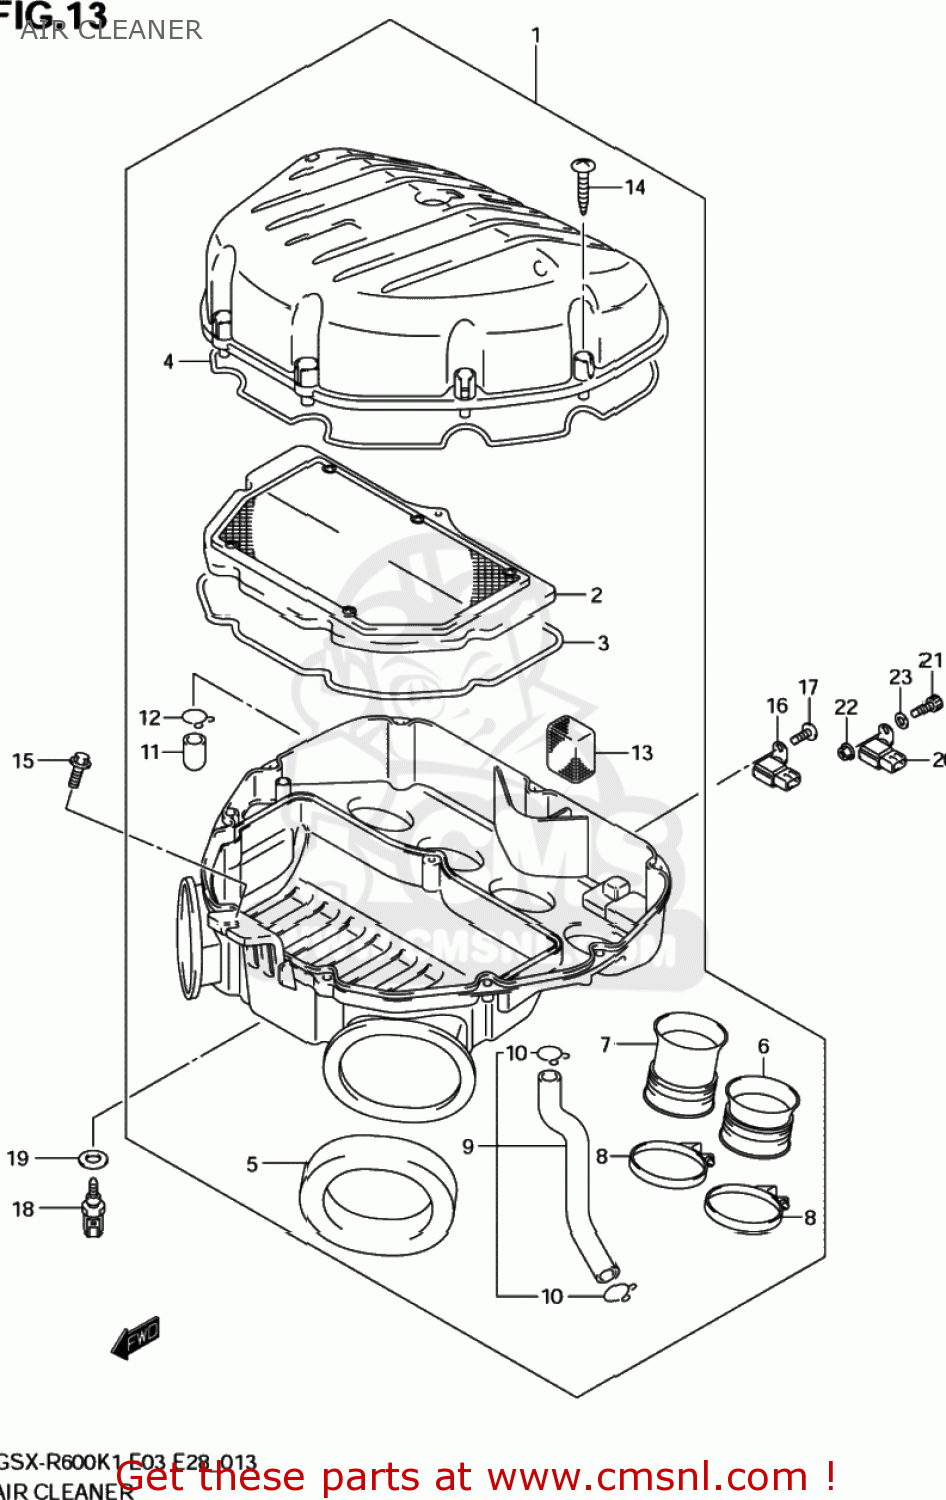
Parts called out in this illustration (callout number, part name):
1	CLEANER ASSY,A
2	FILTER ASSY,AIR CLEANER
3	GASKET,CASE (NAS)
4	GASKET,CAP (NAS)
5	CUSHION,DUCT
6	TUBE,OUTLET A
7	TUBE,OUTLET B
8	CLAMP
9	TUBE,BREATHER
10	CLIP
11	PLUG
12	CLIP
13	FILTER,BREATHER
14	SCREW
15	BOLT(6X16)
16	SENSOR,BOOST
17	SCREW 6X10
18	SENSOR,WATER TEMP
19	GASKET(12X17X1) (NAS)
20	SENSOR,BOOST
21	BOLT,OIL FILLE
22	NUT
23	WASHER(6.5X20X1.2)
